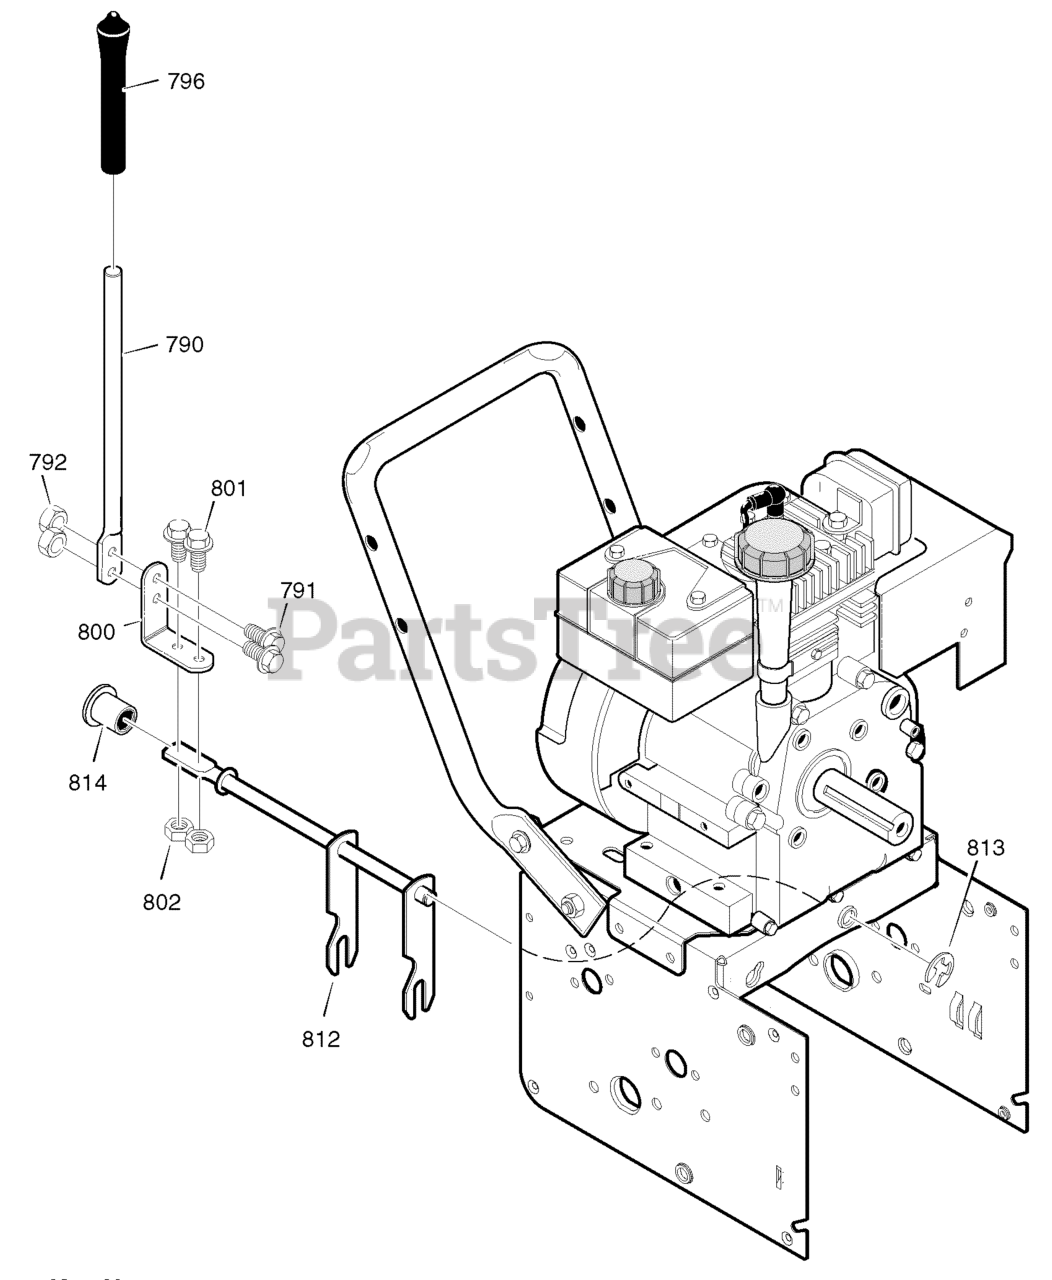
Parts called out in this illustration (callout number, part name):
790	ROD, SHIFT
791	SCREW, 1/4-20X.75
792	NUT, 1/4-20
796	KNOB, SLIP
802	NUT, 1/4-20
812	YZ ROD ASSY., SPEED SELECT
813	RETAINER, RING
814	BEARING, FLANGED
